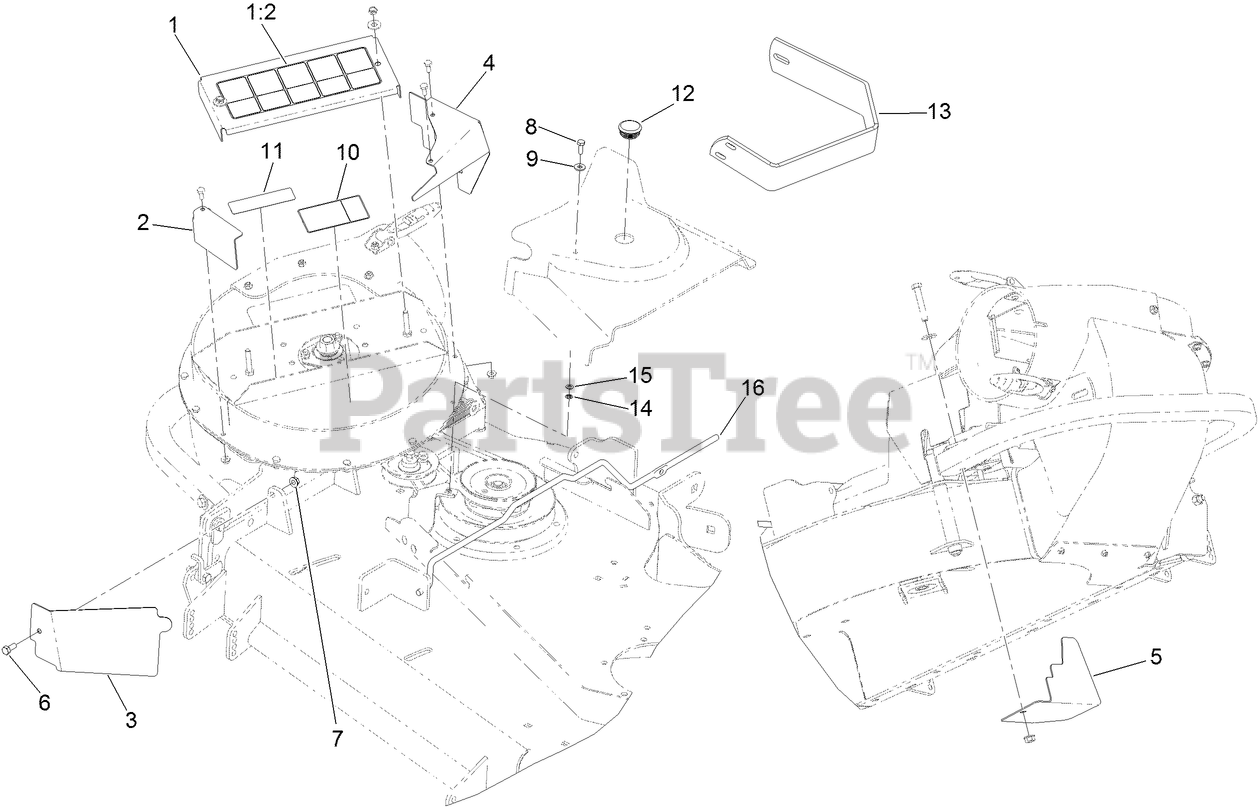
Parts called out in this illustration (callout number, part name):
1	BEARING COVER ASM
1:2	DECAL-DANGER
2	GUARD-LEFT
3	GUARD-FRONT
4	GUARD-BACK
5	GUARD-LOWER
6	SCREW-HH
7	NUT-HF
8	SCREW-HH
9	WASHER-FLAT
10	DECAL-WARNING
11	DECAL-MISSING, COVER
12	PLUG-PLASTIC
13	GUARD-MUFFLER
14	NUT-RETAINER
15	WASHER-FLAT
16	ROD-SUPPORT, LOWER
